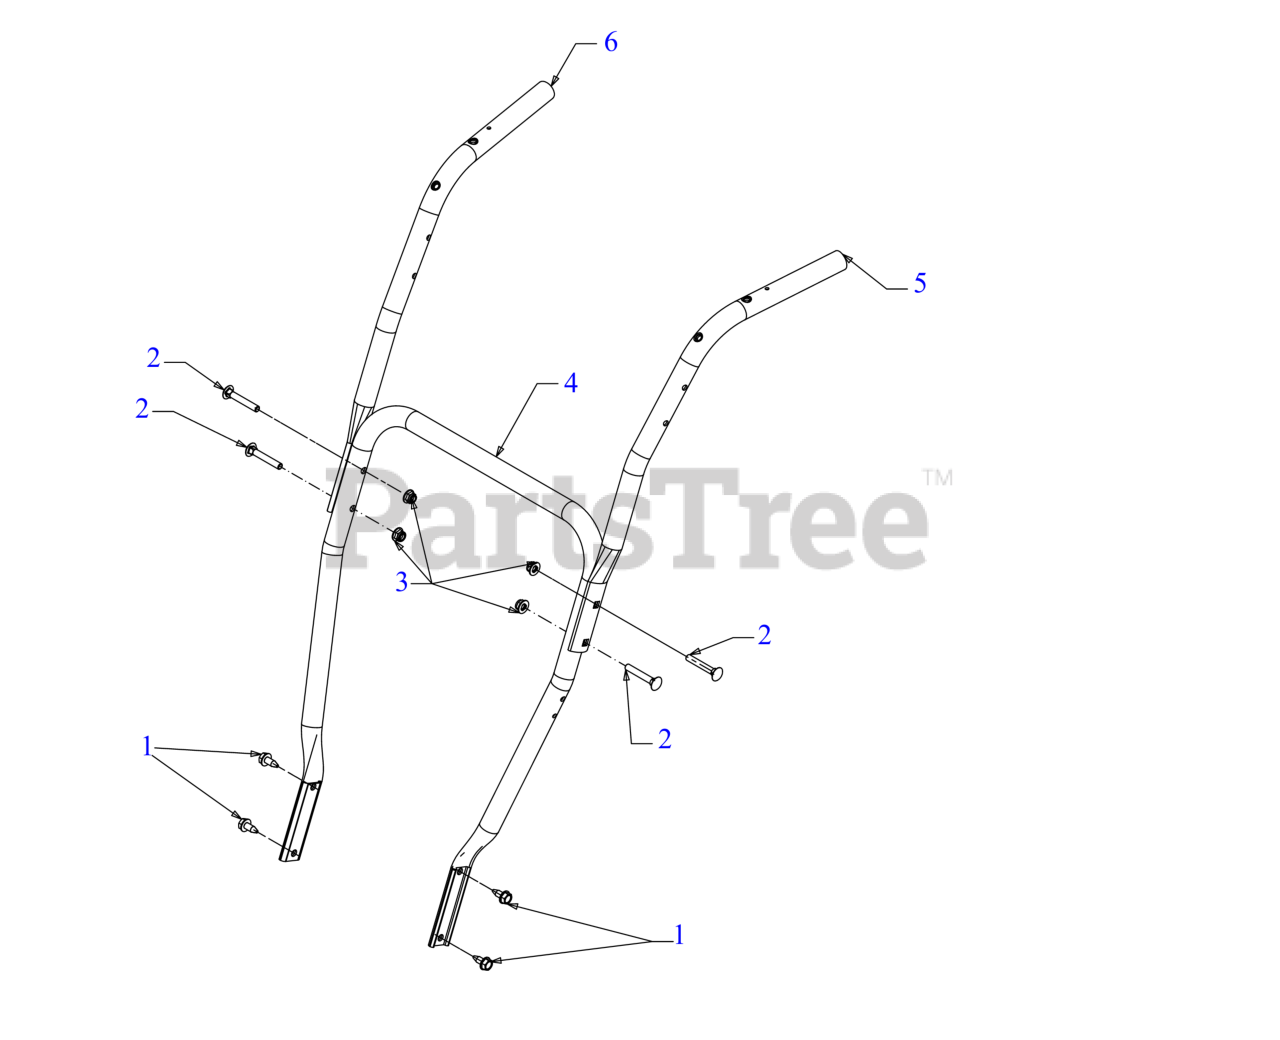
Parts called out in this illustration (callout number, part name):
1	SCREW 5/16-18 x .750
2	CARRIAGE BOLT 5/16-18 x 2.00 GR5
3	FLANGE LOCK NUT 5/16-18
5	UPPER HANDLE (LH)
6	UPPER HANDLE (RH)
